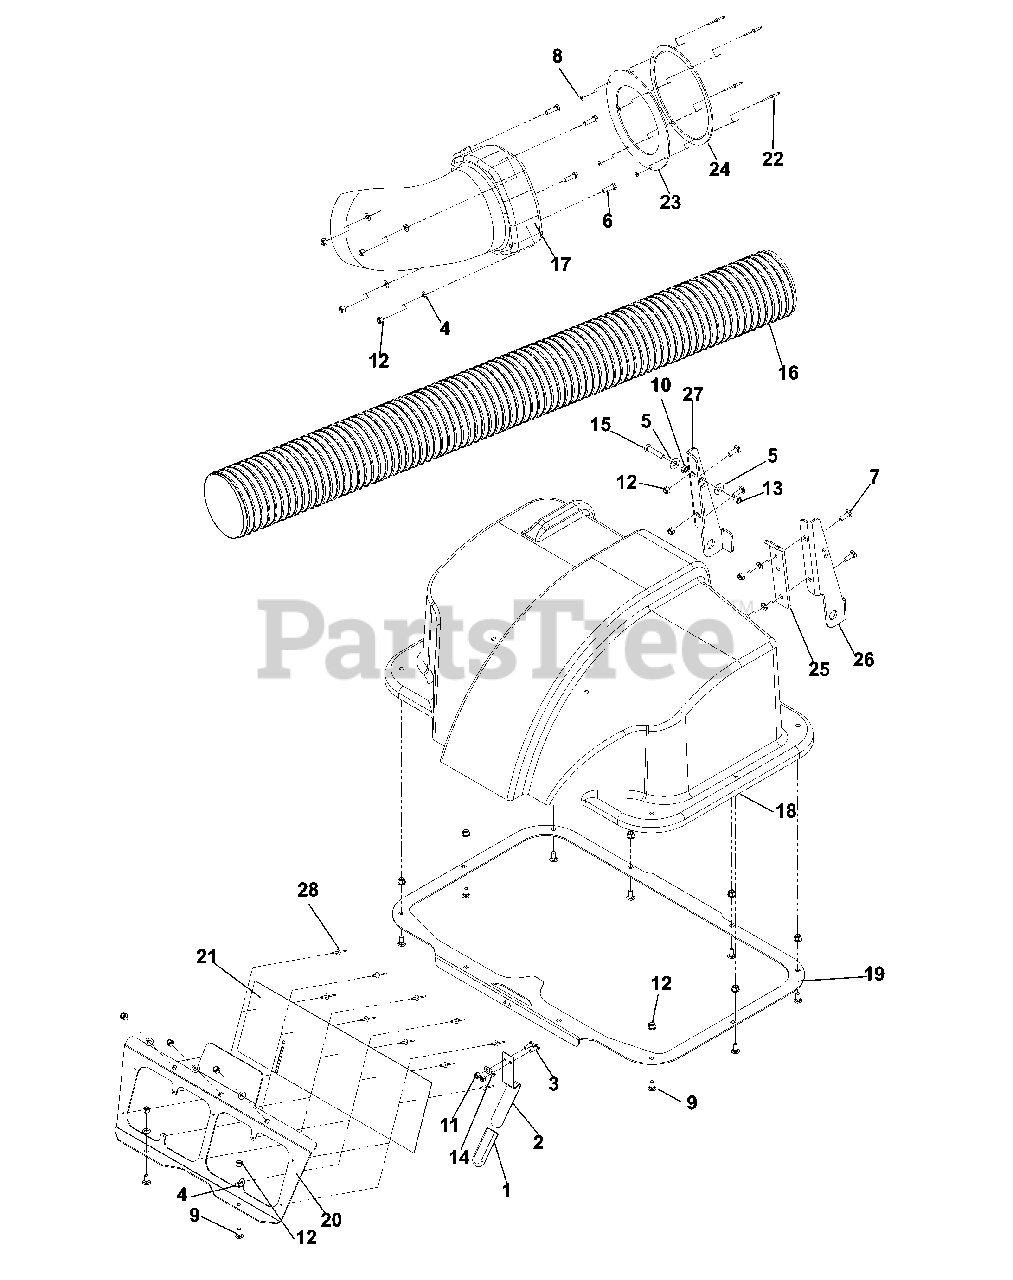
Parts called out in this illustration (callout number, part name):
1	LATCH ROD GRIP
2	G.C. CATCH HANDLE
3	HCS 1/4C X 3/4 HCS
4	FLAT WASHER 5/16 SAE
5	WASHER 3/8 FLAT
6	HCS 5/16C X 1
7	RHSSNB 5/16C X 1.0
8	WASHER .170 I.D.
9	BOLT 5/16C X 3/4" CARRIAGE
10	NUT 3/8-16 HEX JAM
11	NUT 1/4-20 NYLOC
12	NUT 5/16 NYLOC
13	NUT 3/8-16 NYLOC
14	1/4` SAE FLAT WASHER
15	HCS 3/8-16 X 1 3/4 GR5
16	FLEX HOSE 6 X 60
17	INLET TUBE
18	HOOD 2 BAGGER
19	HOOD BOTTOM PLATE
20	RETAINER SCREEN
21	VENT SCREEN
22	5/32 STEEL POP RIVET
23	BAGGER TUBE BOOT
24	BOOT BACKING PLATE
25	CLAMSHELL SUPPORT PLATE
26	RH HINGE PIVOT
27	LH HINGE PIVOT
28	LARGE DOME RIVET
